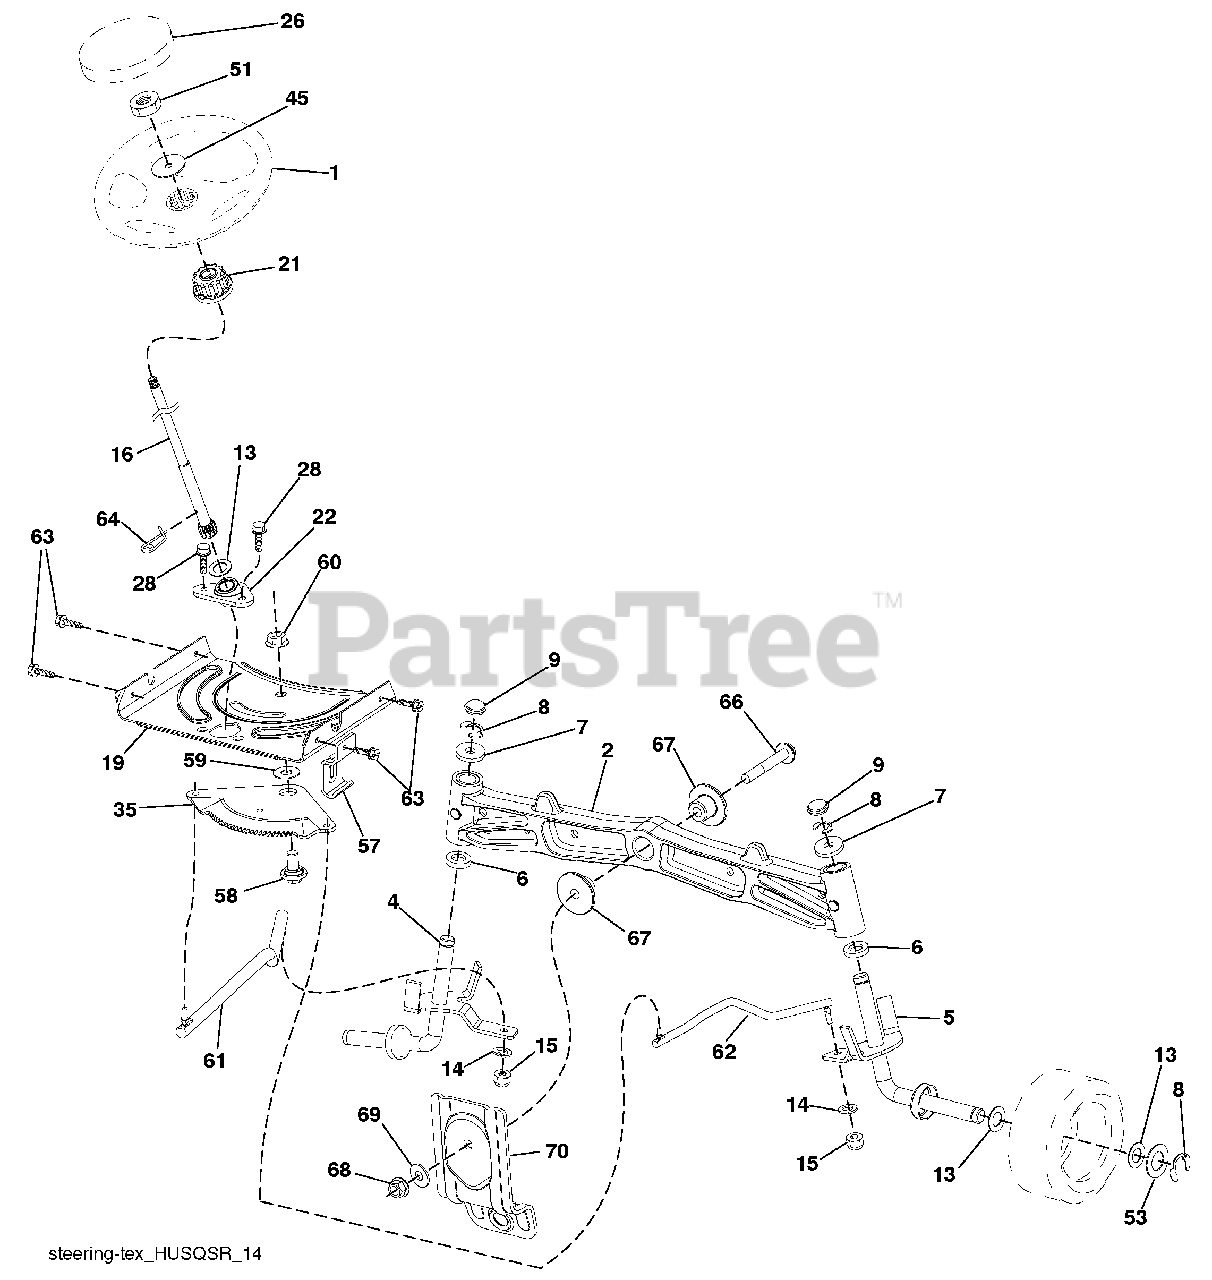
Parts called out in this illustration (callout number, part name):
1	Wheel, Steering
2	Axle Asm., Front
4	Spindle Asm., LH
5	Spindle Asm., RH
6	Bearing, Race Thrust Harden
7	Washer 25/32 x 1-5/8 x 16 Ga.
8	Ring, Klip #T5304-75
9	Cap, Spindle
13	Washer 25/32 x 1-1/4 x 16 Ga.
14	Washer, Lock Hvy Hlcl Spr 3/8
15	Nut, Crown Lock 3/8-24 unf
16	Shaft Steering
19	Plate Steering
21	Adapter, Wheel Steering
22	Strg. Supt. lower
26	Insert, Wheel Steering
28	Screw 3/8-16 x 3/4
35	Gear, Sector Plate
45	Washer 9/16 x 2-3/8 x 12 Ga.
51	Nut Hex Jam Toplock 1/2-20 unf
53	Washer Hardened .793 x 1.637 x .060
57	Bracket Upstop
58	Bolt Shoulder Sector Pivot CFM
59	Washer Thrust Sector Steering
60	Nut Flange Lock 5/8-11
61	Draglink LH
62	Draglink, RH
63	Screw 5/16-18 x 3/4
64	Retainer Clip Spring Steering
66	Bolt Hex Fghd 7/16-14 x 3 Serr
67	Bushing PM Front Axle
68	Nut Lock Flange 7/16-14 Gr. 5
69	Washer 1.5 x .505 x .118
70	Bracket Deck Susp. Front
